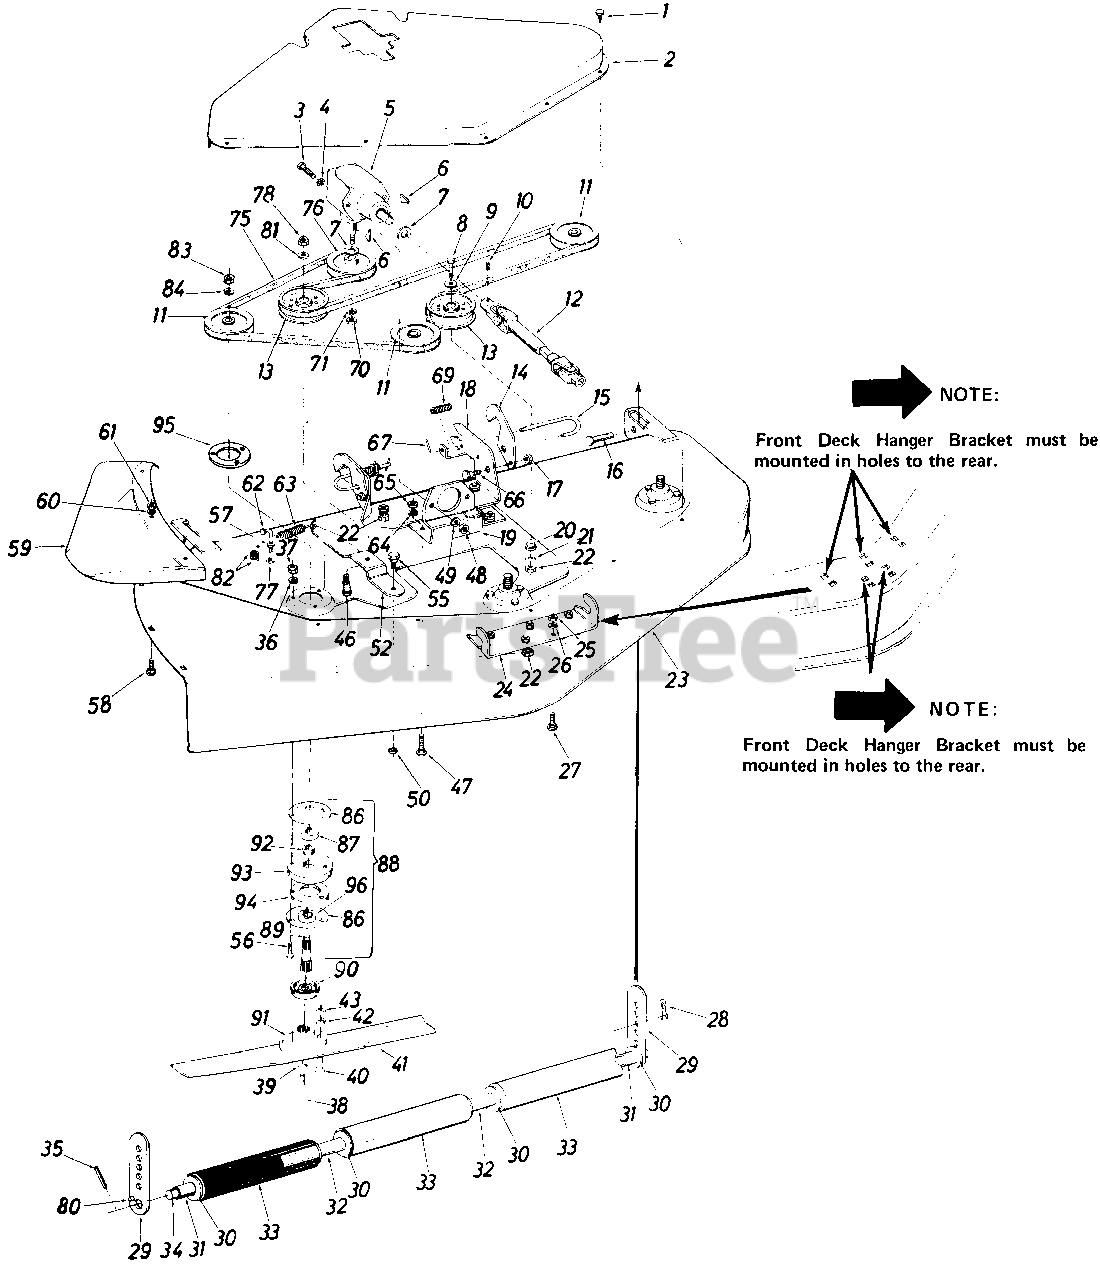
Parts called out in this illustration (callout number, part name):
1	Hex B Tap Scr. 1/4-20 x .38" Lg.
4	Ext. L-Wash. 3/8" Scr.
5	Right Angle Drive
6	#9 Hi-Pro Key 3/16 x 3/4" Dia.
7	Fl-Wash. 29/32 I.D.
8	Hex Scr 3/8 16 x 2.25" Lg.
9	Fl-Wash. 3/8" I.D.
10	Sq. Hd. Set Scr. 3/8-16 x .50" Lg. Cup
11	Deck Pu I ley
12	Universal Drive Shaft Ass'y.
13	Deck Idler Pulley
14	Hanger Lock
15	Release Pin
16	Clevis Pin .500 Dia.
17	Hex Cent. L-Nut 5/16-18 Thd.
21	L-Wash. 3/8" Scr.
22	Hex Nut 3/8-16" Thd.
26	L-Wash. 5/16" Scr.
27	Carriage Bolt 5/16-18 x 1.00" Lg.
28	Internal Cotter Pin
30	Fl-Wash. .75 I.D. x 1.5 O.D.
31	Spacer .758 I.D. x 1.25 O.D. x .530
34	Roller Shaft
35	Roll Pin 3/16 x 1.25
36	L-Wash. 5/16" Scr.
37	Hex Cent. L-Nut 5/16-24 Thd.
38	Hex Scr. 3/8-24 x .75" Lg. Thd. Rolling
39	L-Wash. 3/8" Scr. H.D.
40	Hex Scr. 5/16-24 x 1.00" Lg.
41	Blade 17"
42	L-Wash. 5/16" Scr.
43	Hex Cent. L-Nut 5/16-24 Thd.
46	Hex Scr. 5/8-18 x 1.31" Lg.
47	Carriage Bolt 5/16-18 x .75"
48	Hex Nut 3/8-16 Thd.
49	L-Wash. 3/8" Scr.
50	Hex Cent. L-Nut 7/16-14
56	Hex Scr. 5/16-24 x 1.50" Lg. (Grade 5)
57	Hex Nut 1/4-20Thd.
58	Carriage Bolt 5/16-18 x .75 Lg.
60	L-Wash. 5/16" Scr.
61	Hex Nut 5/16-18 Thd.
62	Hook Bolt
63	Extension Spring
64	L-Wash. 5/16" Scr.
65	Hex Nut 5/16-18 Thd.
66	Shld. Scr.
67	Roll Pin 1/8" Dia.
69	Compression Spring
70	Hex Cent. L-Nut 5/8-18 Thd.
71	L-Wash. 5/8" Scr.
75	"V"-BeltASect. 117" Lg.
76	Drive Pulley
77	Hex Cent. L-Nut 1/4-20 Thd.
78	Hex Cent. L-Jam Nut 5/8-18 Thd.
80	Spring Pin Spiral 1/4" Dia. 1.00" Lg.
81	Fl-Wash. .62" I.D.
82	Ext. L-Wash. 1/4" Scr.
83	Hex Jam Nut 5/8-18 Thd.
84	L-Wash. 5/8" I.D.
86	Bearing Housing
87	Ball Bearing
88	Deck Spindle Ass'y.
89	Spindle
90	Bearing Shield
91	Blade Adapter
92	Spacer
93	Spindle Spacer Plate
94	Reinforcement Plate
95	Spindle Reinforcement Plate
96	Open Bearing Housing
